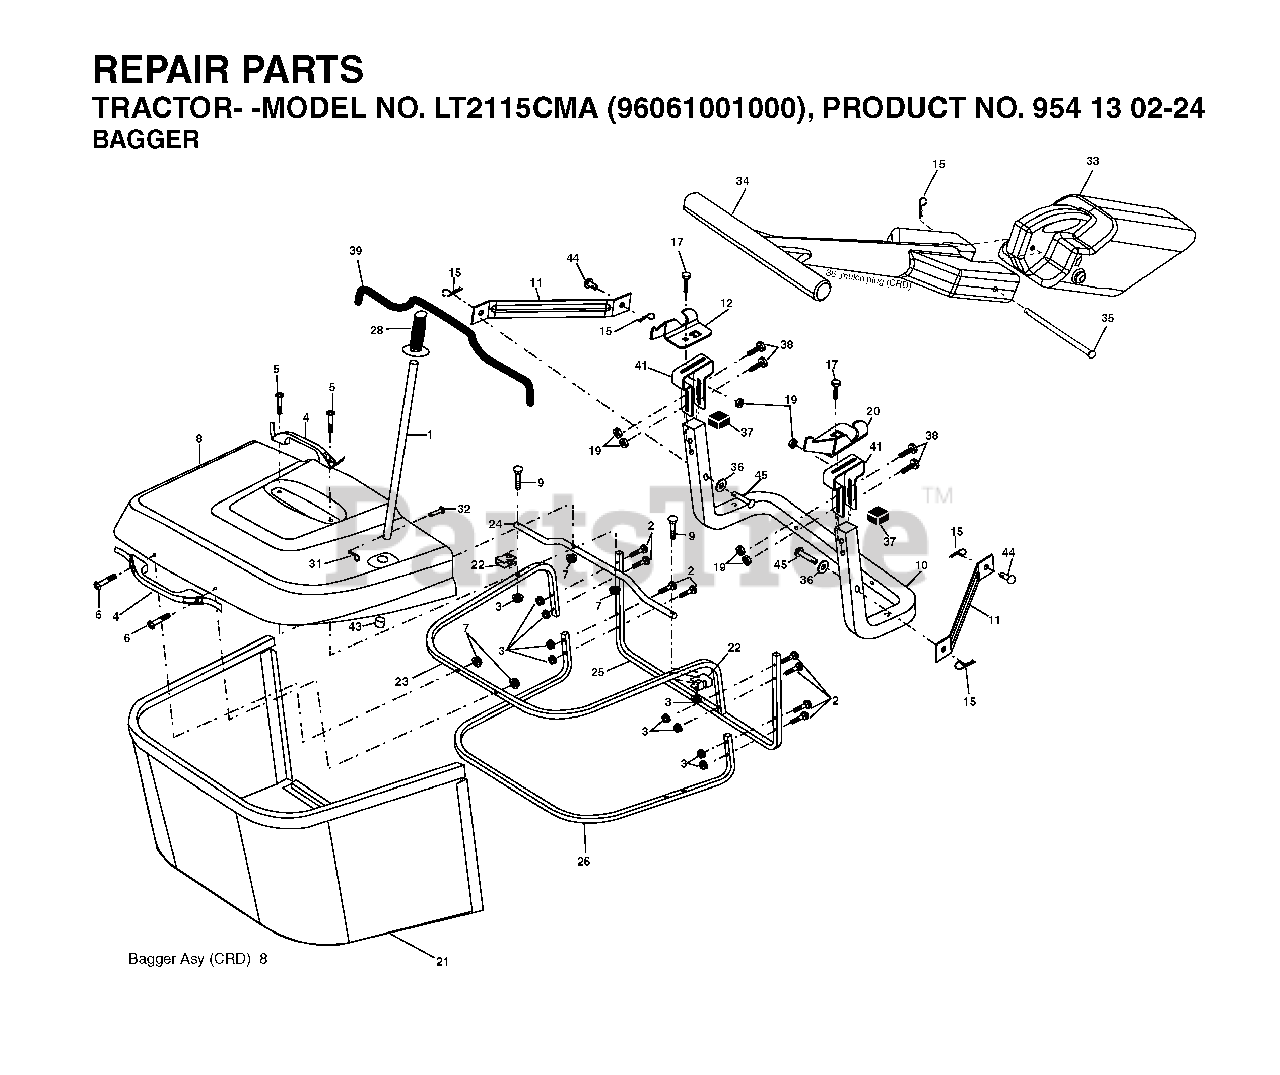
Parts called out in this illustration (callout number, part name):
1	TUBE HANDLE
3	NUT T
5	SCREW.PAN.HEAD
11	BRACKET
15	RETAINER-SPRNG RB
17	BOLT
19	NUT LOCK HEX FLANGE 5/16-18
20	BRKT.PIVOT.RH.CRD
21	GRASS BAG
22	BRACKET
23	TUBE
24	TUBE
26	TUBE
28	GRIP.HANDLE.BLACK
31	RETAINER CLIP
32	RIVET,DRILLED
33	PLUG
35	PIN
38	BOLT.5/16-18X2.5
41	BRKT, BAGGER
43	PLUG, TUBING END
